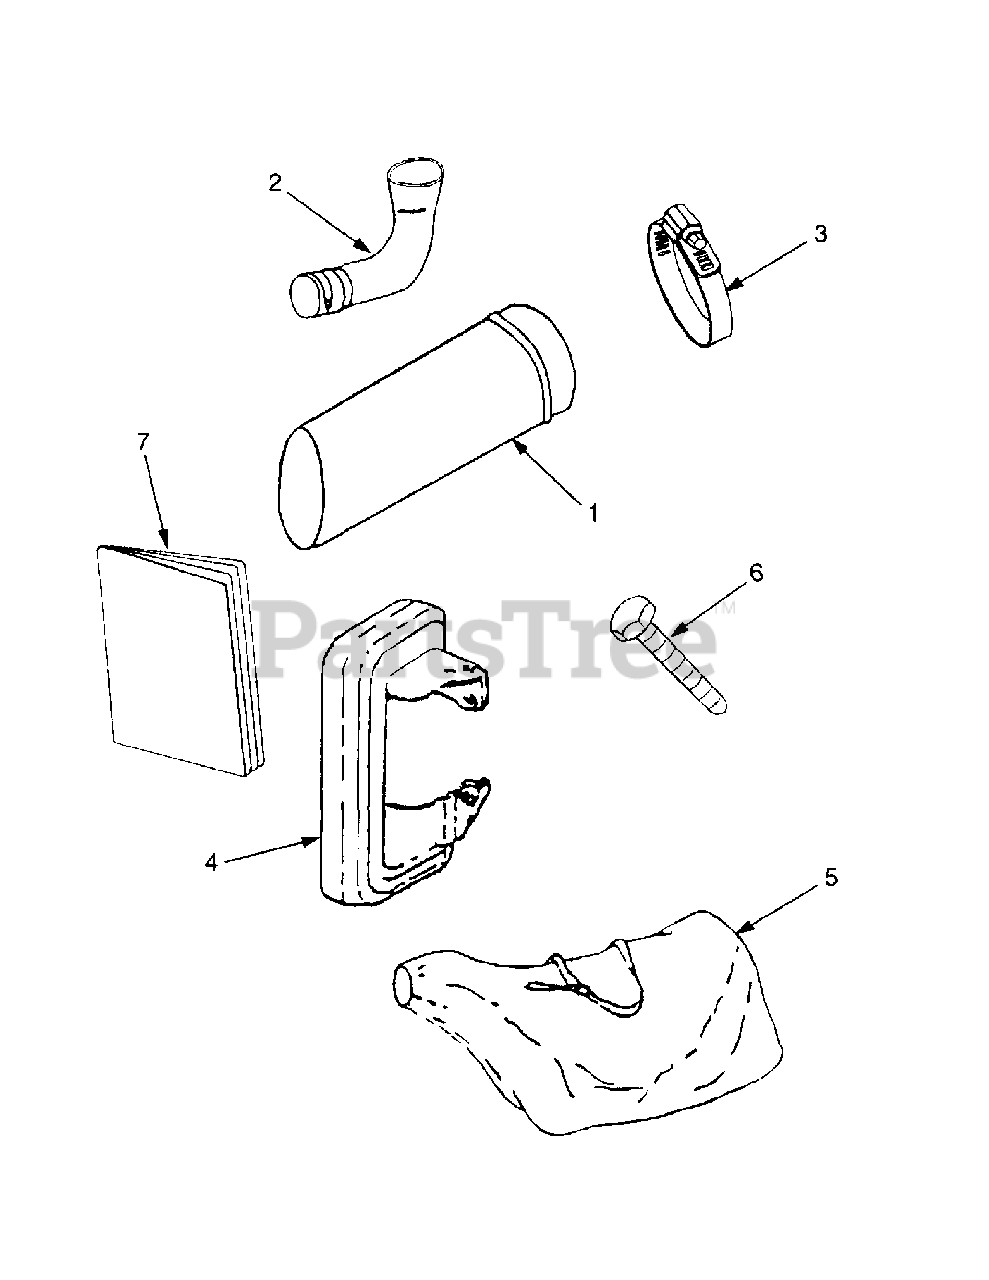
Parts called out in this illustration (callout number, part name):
1	Straight Pipe
2	Curve Pipe
4	Grip Handle
5	Vacuum Bag
6	Bolt, M5 x 25
7	Instruction Book
